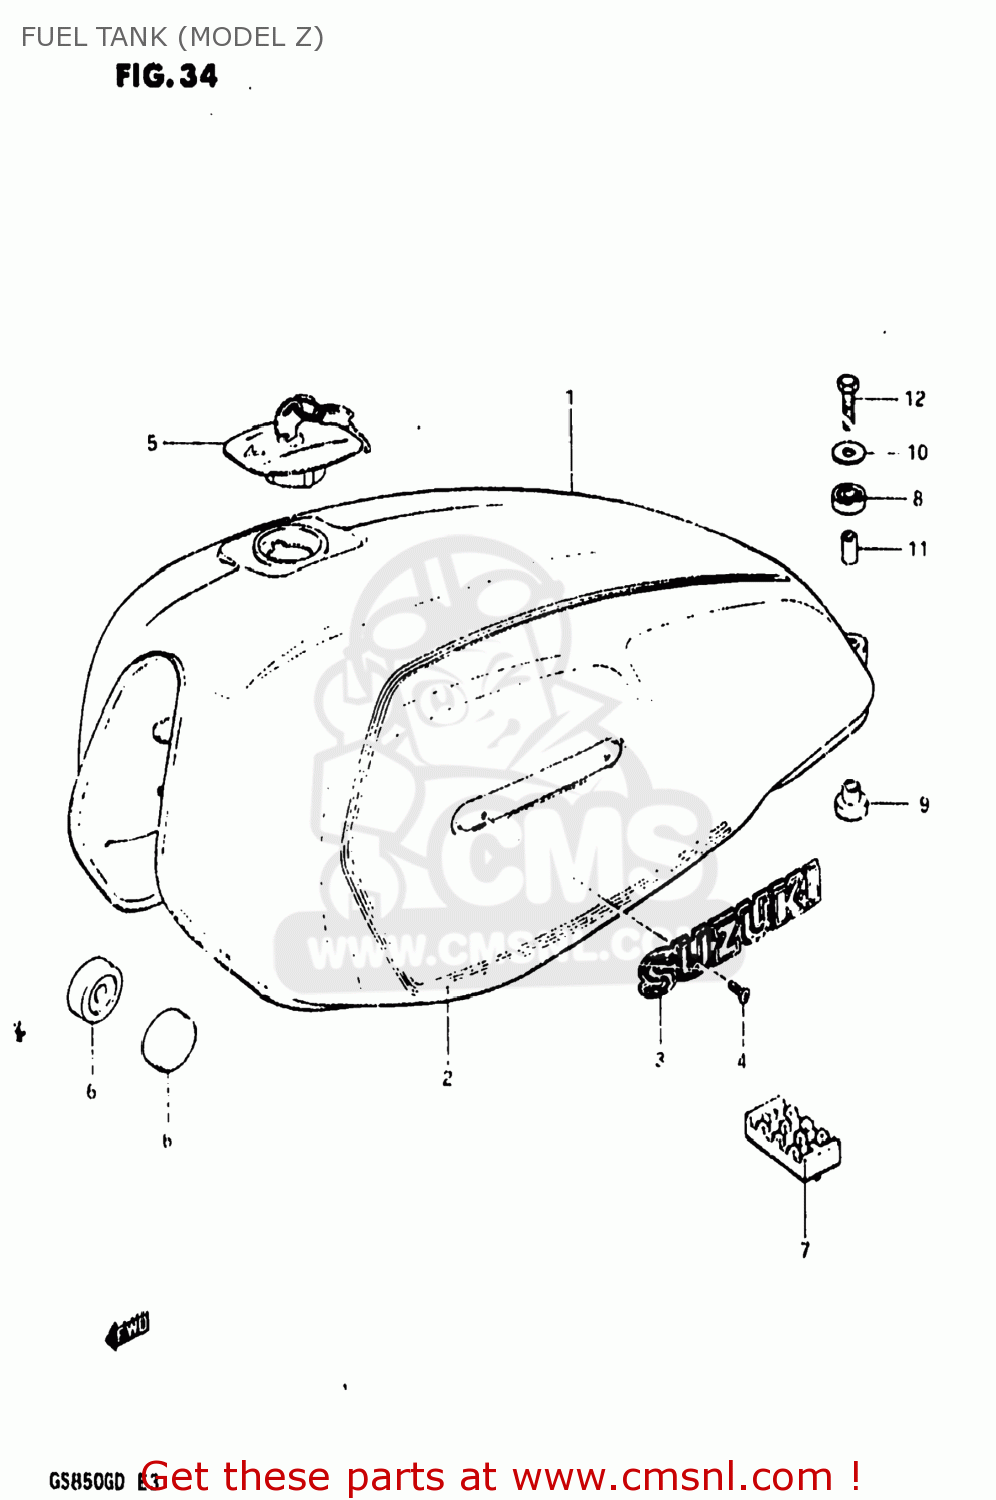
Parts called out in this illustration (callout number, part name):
1	TANK ASSEMBLY,FUEL
2	TAPE SET,FUEL TANK
3	EMBLEM
4	SCREW 3X6
5	CAP SET,FUEL TANK
6	CUSHION
7	CUSHION,FUEL TANK
8	CUSHION
9	CUSHION
10	WASHER (6.5X24X1.6)
11	SPACER (6.4X9X21.5)
12	BOLT
